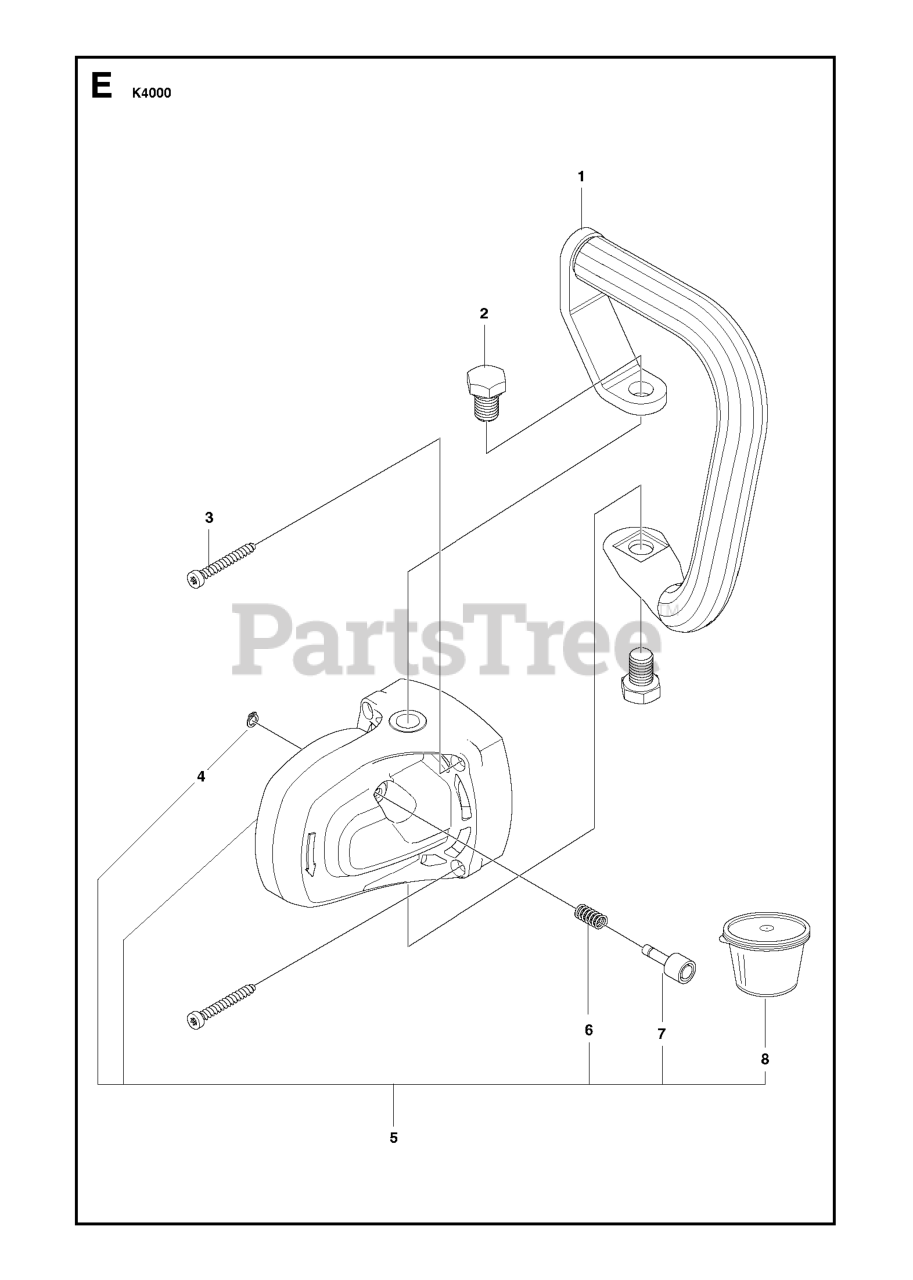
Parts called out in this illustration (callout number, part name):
4	SEEGER CLIP
6	SPRING, GEAR LOCK
8	BEVEL GEAR GREASE
